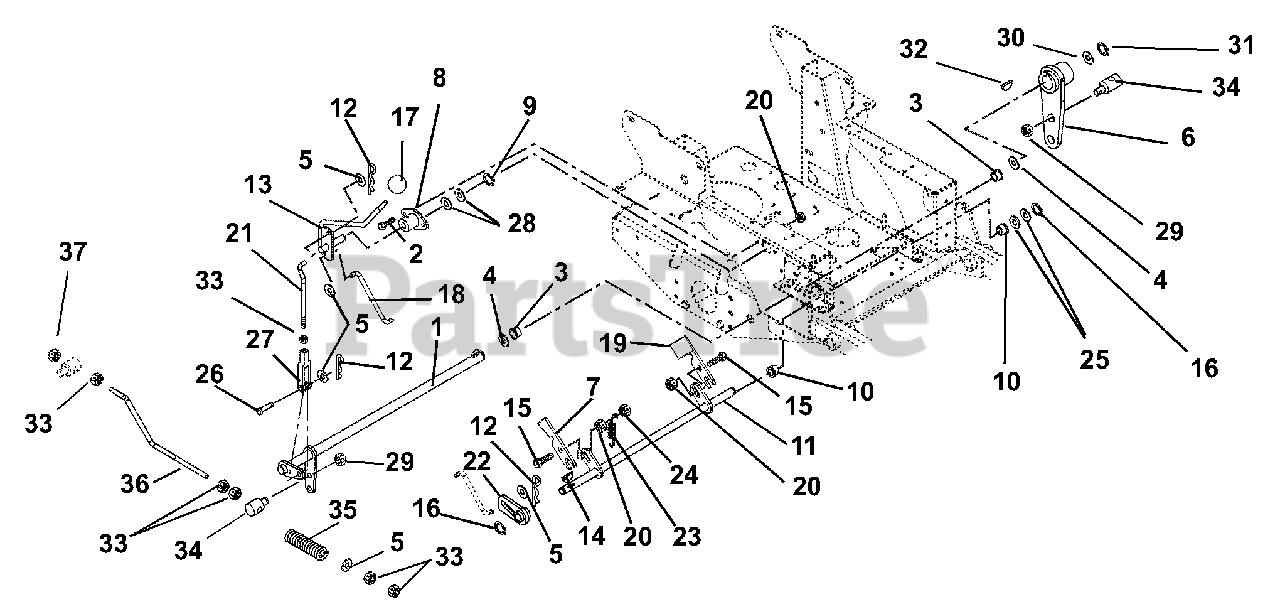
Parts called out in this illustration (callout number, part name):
1	Weldment, Brake Pivot
2	Bolt, Hex .31-18 x 1.00 Grade 5
3	Bushing, Flange .762 x 1.00 x .58 x 1.48 Nylon
4	Washer, Flat Steel .812 x 1.50 x .135
5	Washer, Flat Steel .406 x .812 x .065
6	Weldment, Brake Arm
7	Slide, Interlocking Brake
8	Bushing, Flange
9	Ring, Retaining External .625 x .05
10	Bushing, Flange .515 x .75 x .745 x 1.00
11	Weldment, Mechanical Brake
12	Pin, Hair
13	Weldment, Brake Actuating
14	Key, Woodruff .13 x .63
15	Bolt, Round Head Square Neck .31-18 x 1.25 Grade 5
16	Ring, Retaining External .50 x .05
17	Knob, Steering Lock
18	Linkage, Brake Actuating
19	Interlock, Safety Switch
20	Nut, Nyloc Flange 5/16-18
21	Linkage, Brake Compact-Z
22	Weldment, Parking Brake Hub
23	Spring, Tension .061 x .50 x 3.0
24	Nut, Locking Center .31-18
25	Washer, Flat Steel .505 x 1.00 x .062
26	Pin, Clevis .38 x 1.25
27	Clevis, .38-24 Adjustable
28	Washer-Flat-Steel .630 x 1.250 x .062
29	Nut, Center Lock Nut, .31-18
30	Washer-Flat-Steel .755 x 1.375 x .062
31	Ring, Retaining External .689 x .078
32	Key-Woodruff .19 x .75
33	Nut, Jam .375-24
34	Pin, Pivot
35	Spring, Compression .143 x .710 x 2.00
36	Linkage, Brake
37	Nut, Locking Center .375-24
